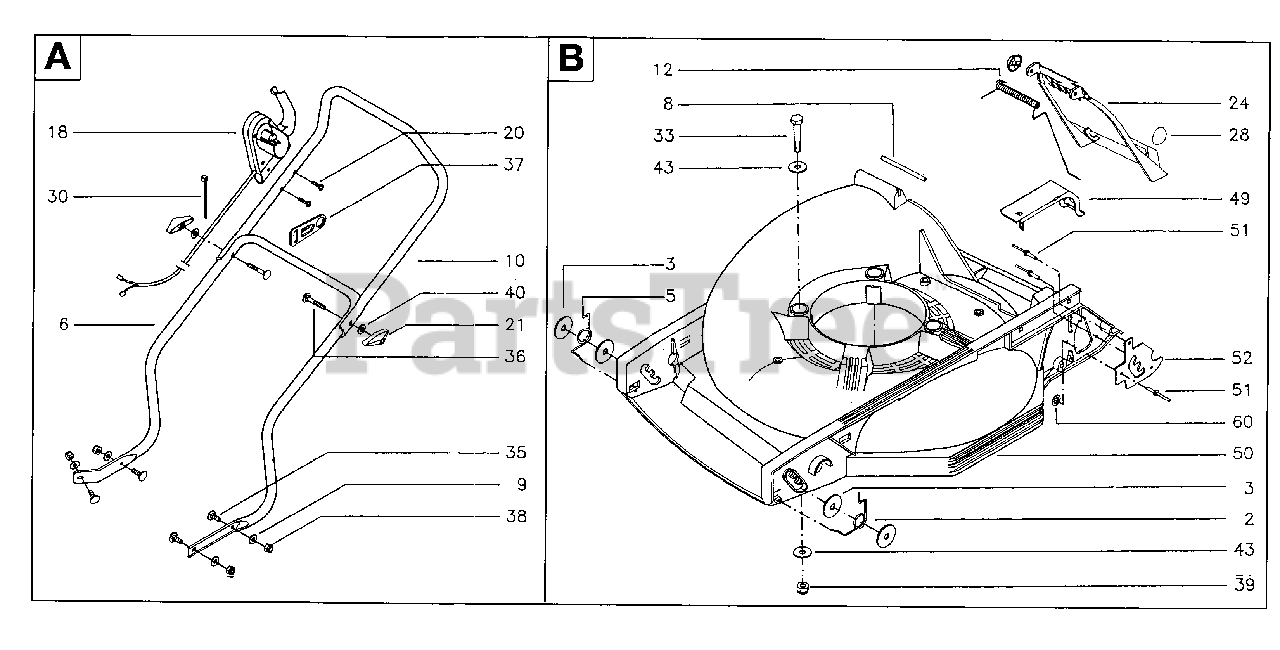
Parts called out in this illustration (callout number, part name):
38	LOCKNUT M6
39	LOCKNUT M8
40	WASHER - 15X7.3X1.6
60	WASHER
